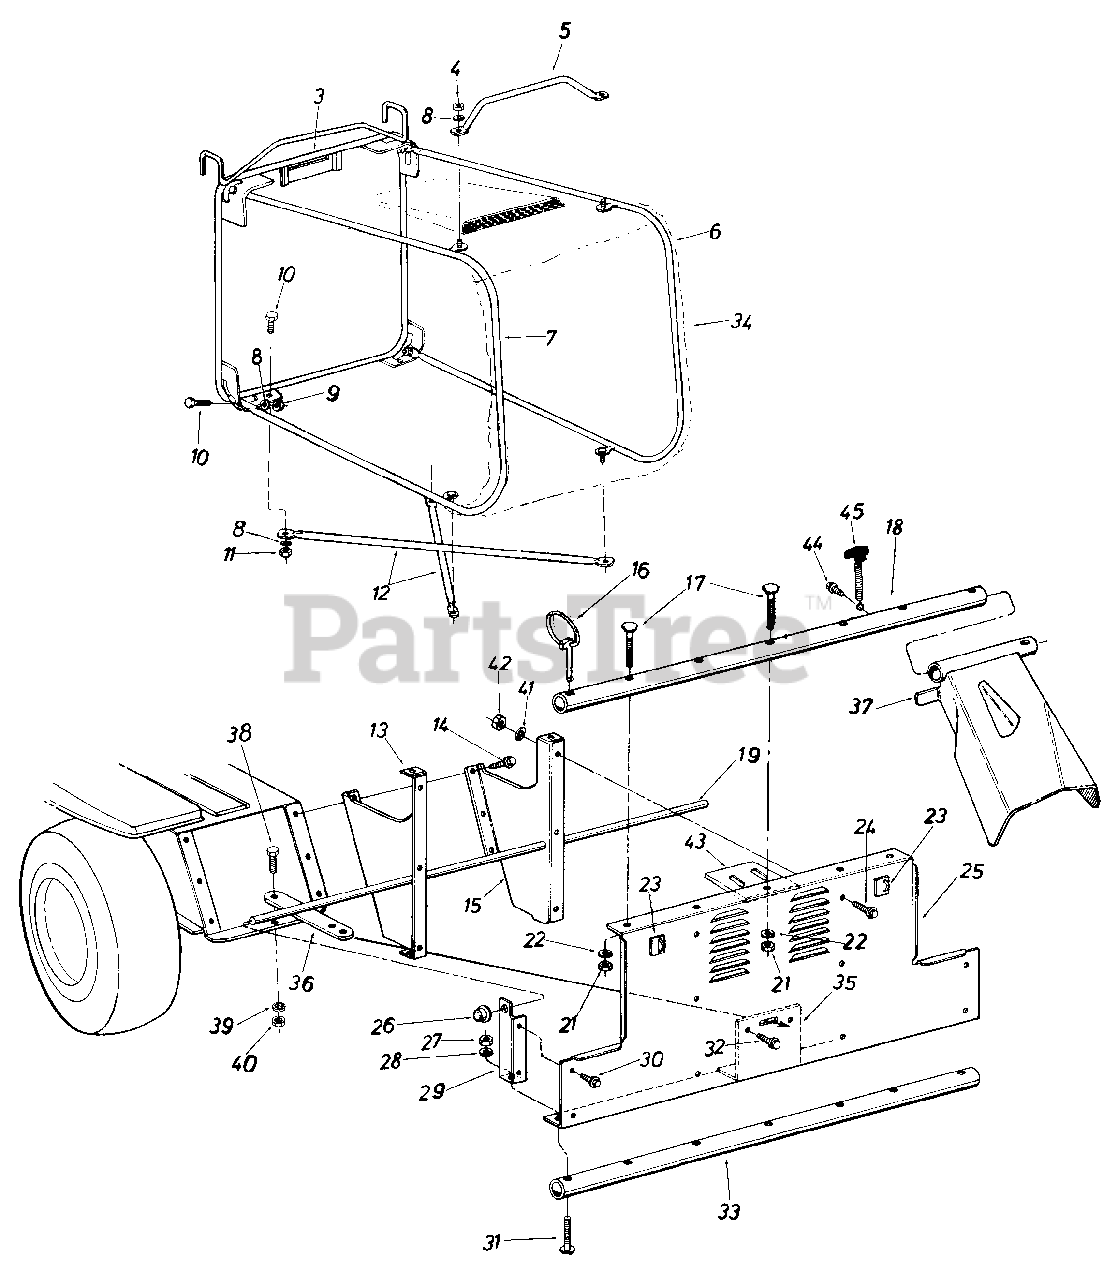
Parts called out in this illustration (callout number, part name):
3	Grass Catcher Frame Ass'y.
4	Hex Cent. L-Nut 1/4-20 Thd.
5	Grass Catcher Handle
9	Hex Cent. L-Nut 1/4-20 Thd.
10	Hex Bolt 1/4-20 x .62" Lg.
11	Hex Cent. L-Nut '14-20 Thd.
12	Bottom Cross Brace
13	Grass Catcher Support Brk't. L.H.
14	Hex Wash. Hd. Self-Tap Scr. 5/1 6-1 8 x .75" Lg.
15	Grass Catcher Support Brk't. R.H.
16	Klick Pin
17	Curved Carr. Bolt 5/16-18 x 1.75" Lg.
18	Grass Catcher Support Tube
19	Tubing .38" I.D. x 39.75" Lg.
21	Hex Nut 5/16-18 Thd.
22	L-Wash. 5/16" I.D.
23	Safety Switch
24	Hex Wash. Hd. Self-Tap Scr. 1/4-20 x .50" Lg.
25	Grass Catcher Adapter
26	Cap Speed Nut 1/2" Rod
27	Hex Nut 5/16-18 Thd.
28	L-Wash. 5/16" I.D.
29	Chute Extension Support Brk't. L.H.
30	Hex Wash. Hd. Self-Tap Scr. 1/4-20 x .50" Lg.
31	Curved Carr. Bolt 5/16-18 x 1.75" Lg.
32	Hex Wash. Hd. Self-Tap Scr. 1/4-20 x .50" Lg.
33	Tubing 1.00" I.D. x 40.25"
34	Grass Catcher Bag
35	Hitch Bracket
39	L-Wash. 1/2" I.D.
40	Hex Jam Nut 1/2-13 Thd.
41	Ext. L-Wash. 1/4" I.D.
42	Hex Nut 1/4-20 Thd.
43	Grass Catcher Support Plate
44	Hex AB-Tap Scr. 1/4-20 x .62" Lg.
45	Spring Latch Ass'y.
